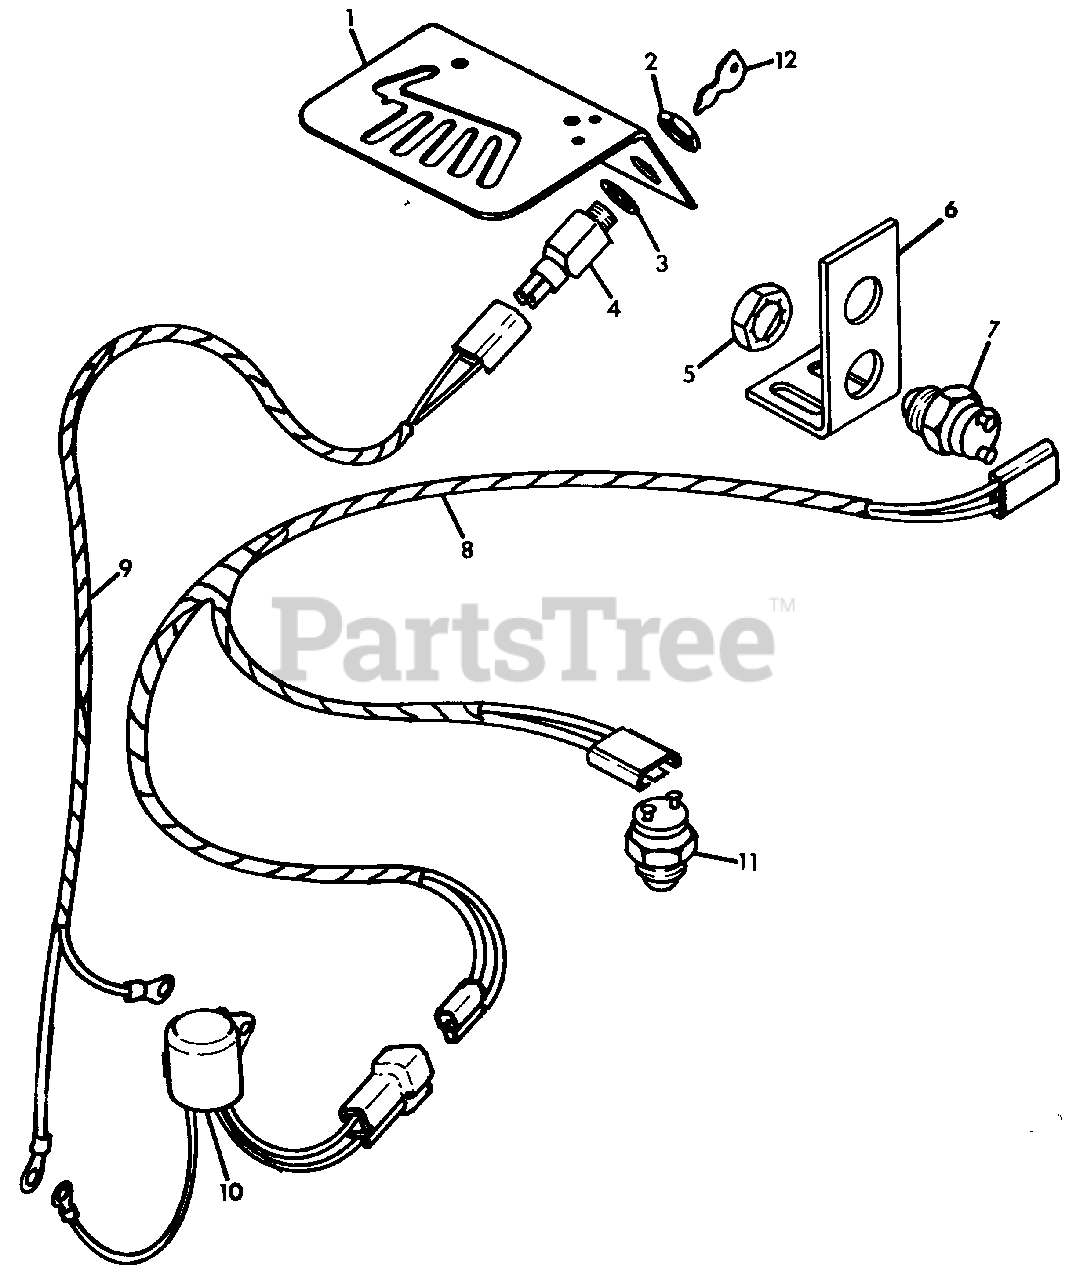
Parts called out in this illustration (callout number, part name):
1	PLATE, INSTRUCTION
2	NUT, JAM 5/8-32
3	WASHER, LOCK 5/8
4	SWITCH, KEY
5	NUT, 9/16-18
6	BRACKET, INTERLOCK SWITCH
7	SWITCH, INTERLOCK
8	HARNESS, WIRING INTERLOCK
9	HARNESS, WIRING SWITCH
10	CONTROL MODULE
11	SWITCH, NEUTRAL START
12	KEY, IGNITION SWITCH
